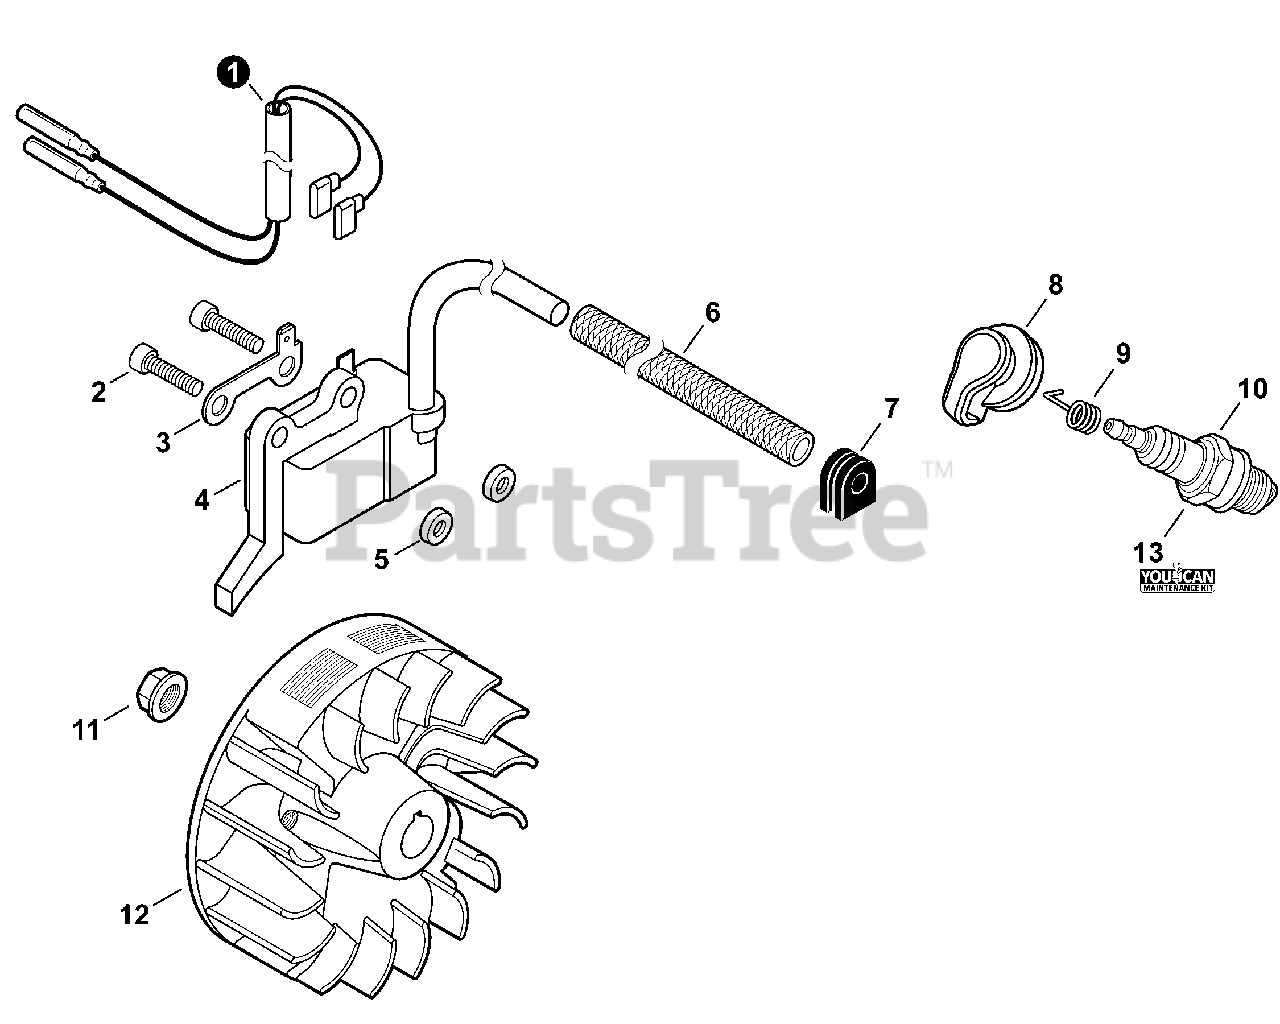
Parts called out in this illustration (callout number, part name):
1	LEAD SET - IGNITION
2	BOLT, TORX 5×20
3	CONNECTOR
4	COIL, IGNITION
5	SPACER 5
6	TUBE, INSULATOR
8	CAP, SPARK PLUG
9	TERMINAL, SPARK PLUG
10	SPARK PLUG - CMR7H
11	NUT, FLANGE M8
12	FLYWHEEL
13	TUNE-UP KIT - YOUCANT
